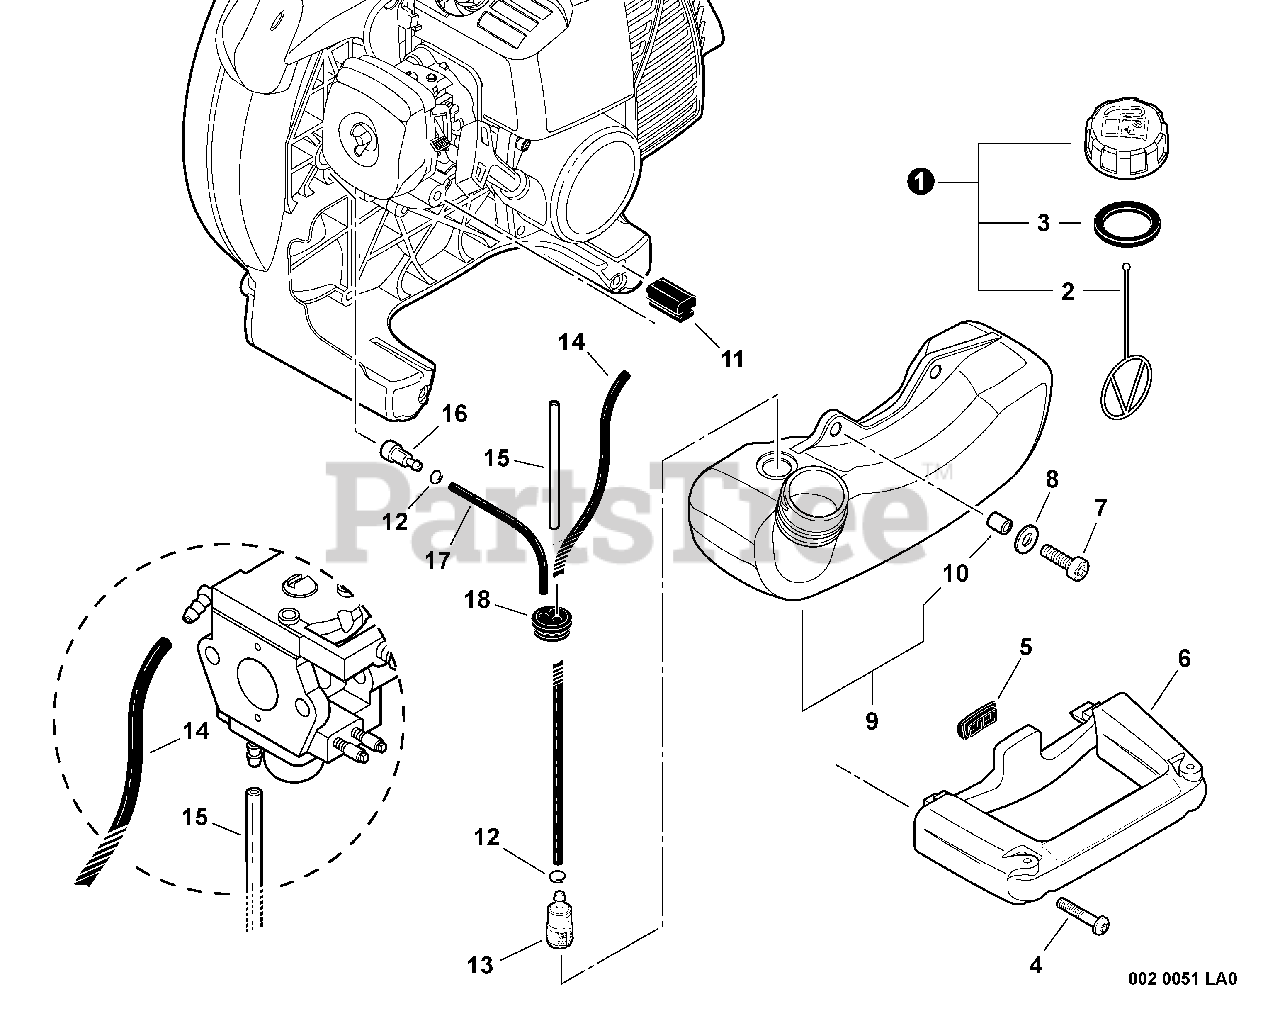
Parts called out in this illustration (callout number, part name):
1	CAP ASSY, FUEL
2	CONNECTOR, CAP L= 100 MM
3	GASKET, FUEL CAP
4	BOLT, TORX 5×25
5	CUSHION
6	HANDLE, REAR
7	BOLT, TORX 5×16
8	WASHER 5.5×12×0.8
9	TANK ASSY, FUEL
10	SPACER 6.2×7.8×6
12	CLIP 6 MM
13	FILTER, FUEL
14	PIPE, FUEL 3×5×210 BLACK
15	PIPE, FUEL 3×6×85 CLEAR
16	VENT ASSY
17	PIPE, FUEL 3×5×80 BLACK
18	GROMMET, FUEL
